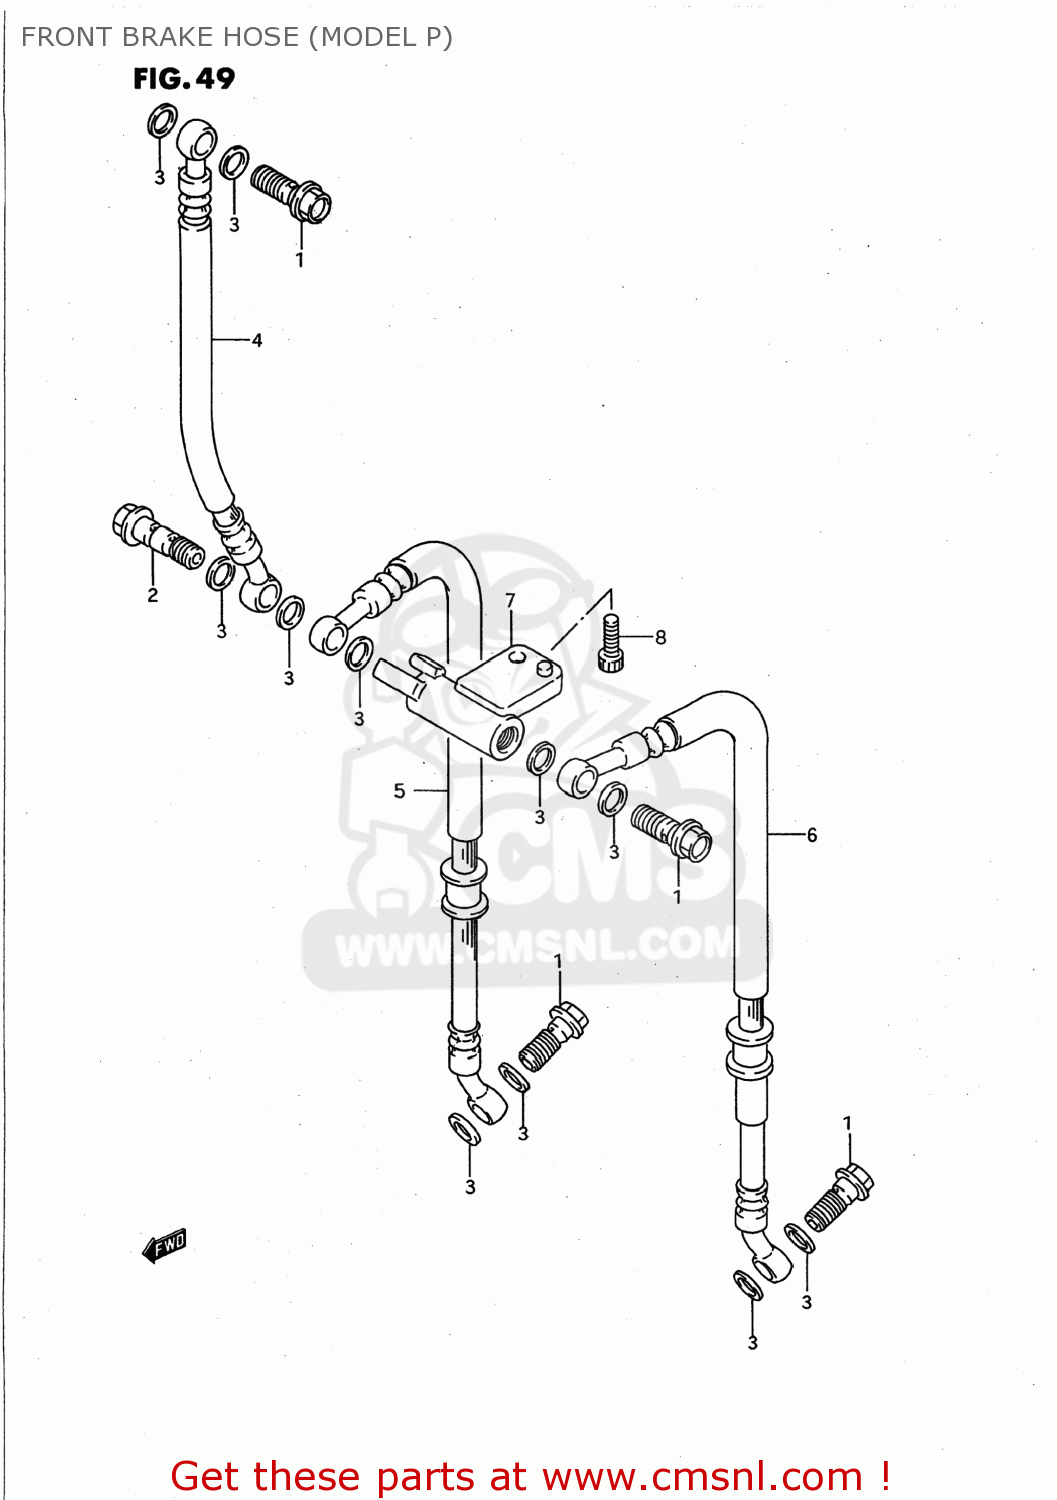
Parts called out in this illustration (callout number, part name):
1	BOLT UNION
2	BOLT UNION
3	WASHER(10X15X1.5)
4	HOSE COMP,FRONT BRAKE
5	HOSE COMP,FRONT BRAKE
6	HOSE COMP,FRONT BRAKE
7	JOINT,BRAKE HOSE
8	BOLT
